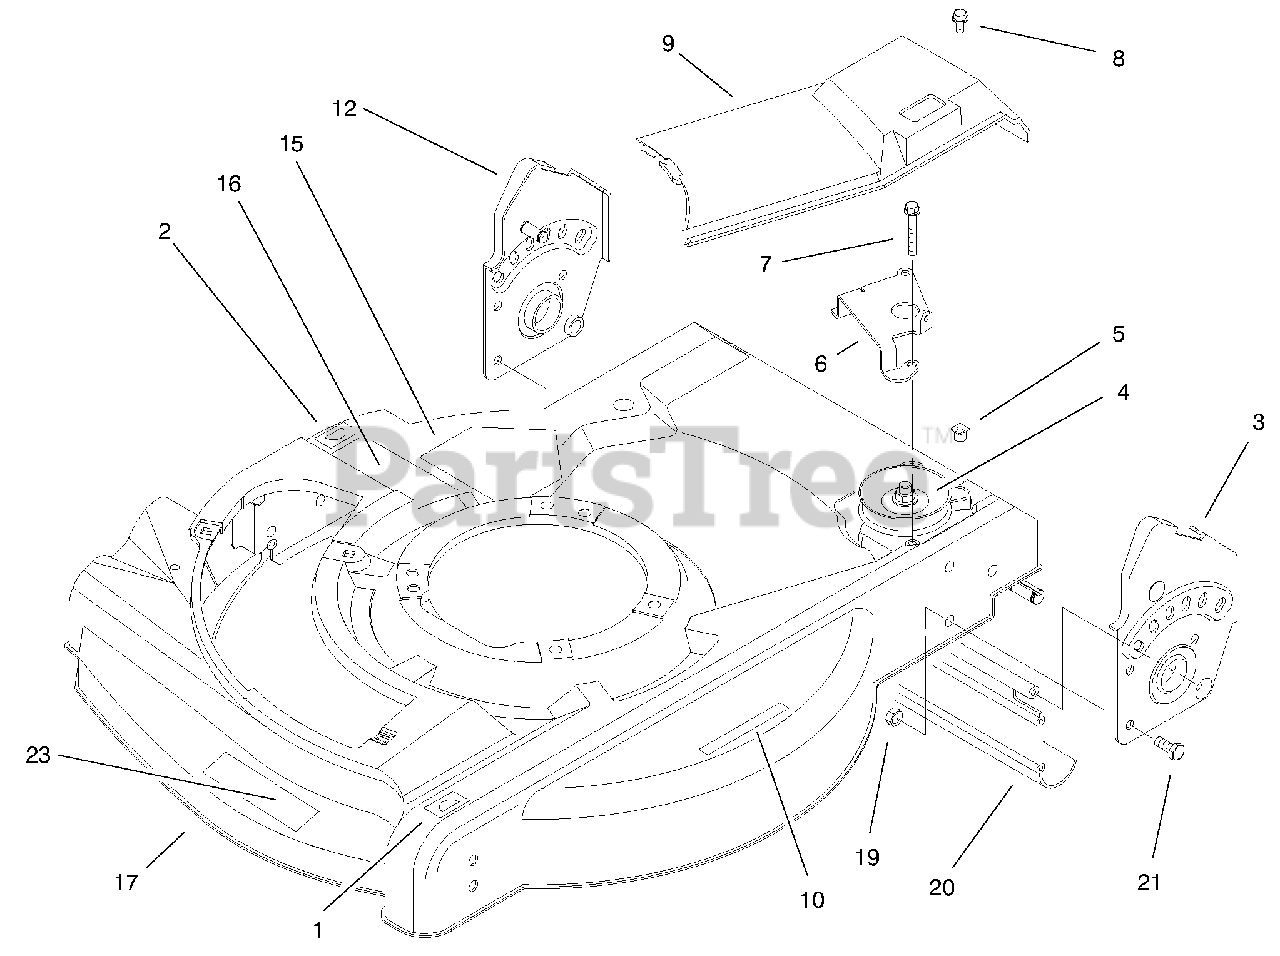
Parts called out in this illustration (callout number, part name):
1	Decal-HOC
2	Decal-HOC
3	ASM-Handle Bracket
4	ASM-Gear Case
5	Grommet
6	Guide-Transmission
7	Torx Head Cap Screw
8	Screw-Phil
9	Cover-Drive
10	Decal-Warning
12	ASM-Handle Bracket
15	Decal-Danger
16	Decal-Discharge
17	ASM-Housing & Baffle/Decals
19	Nut-Lock
20	Shield-Trailing
21	Screw-HH
23	Decal-Deck
